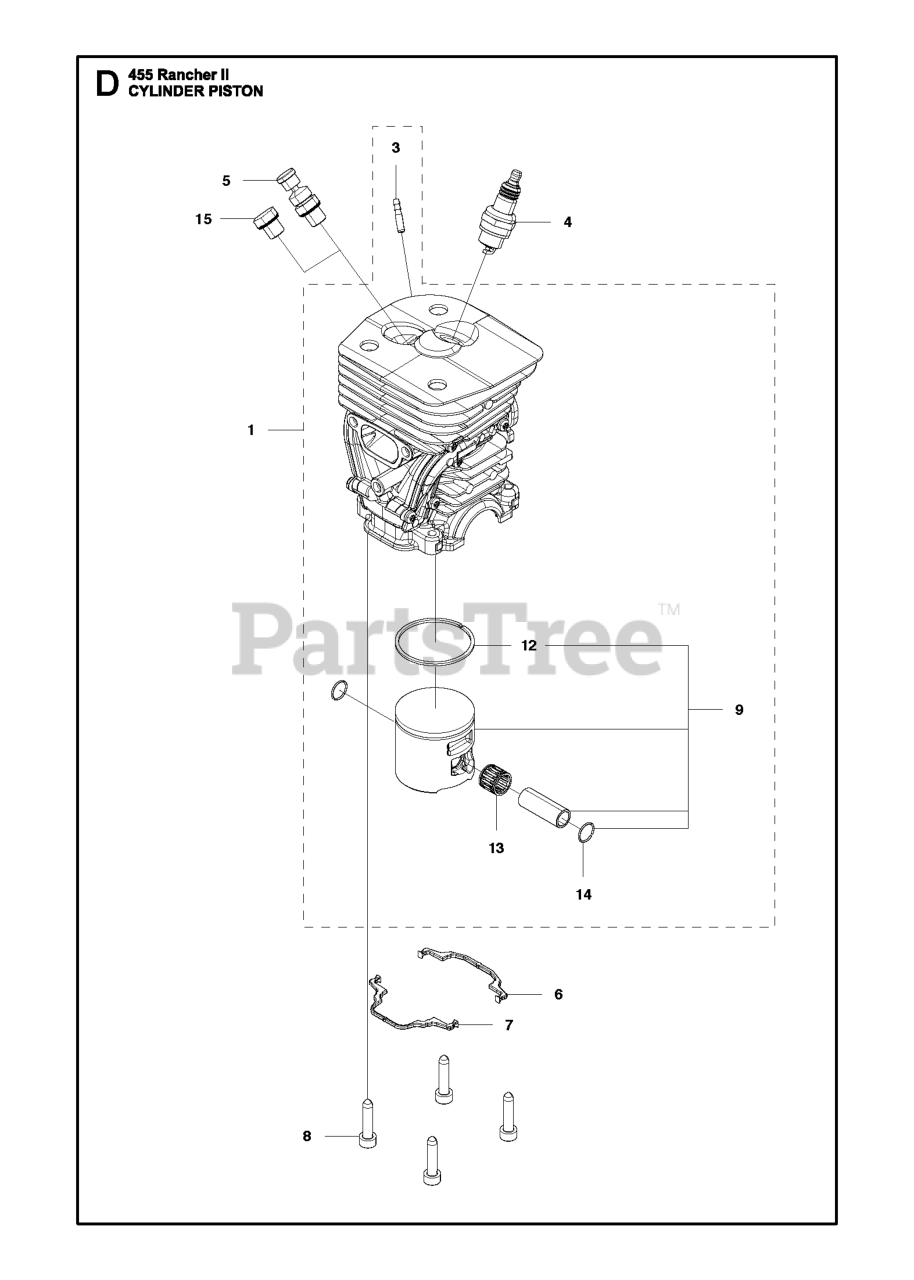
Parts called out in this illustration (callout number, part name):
1	CYLINDER ASSY
4	SPARK PLUG M14X1.25 NGK BPMR7A
8	SCREW
9	PISTON ASSY
12	PISTON RING
13	NEEDLE BEARING
14	CLIP
15	CYLINDER PLUG
